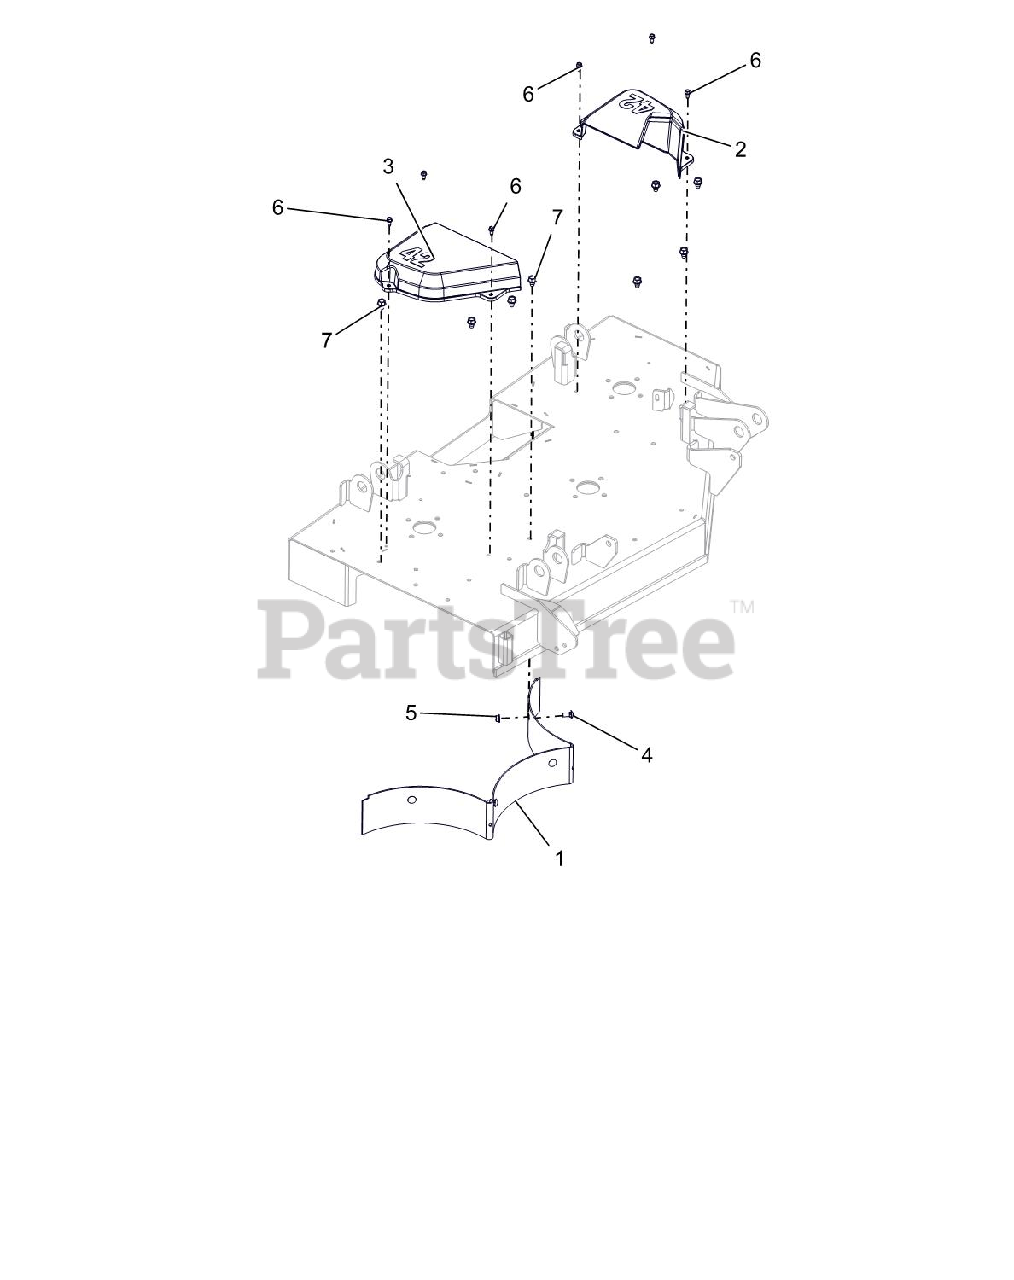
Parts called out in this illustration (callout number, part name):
1	BAFFLE, REAR 42
2	COVER, BELT 42" LH
3	COVER, BELT 42" RH
4	BLT-RDHDSQNK .31-18X.75 G5YZ
5	NUT-LK-TOP-FLG .31-18 YWZC
6	SCR-TAP .25-20X.50 HWH TR YWZ
7	SCR-TAP .38-16X.50 HWH TR YWZ
